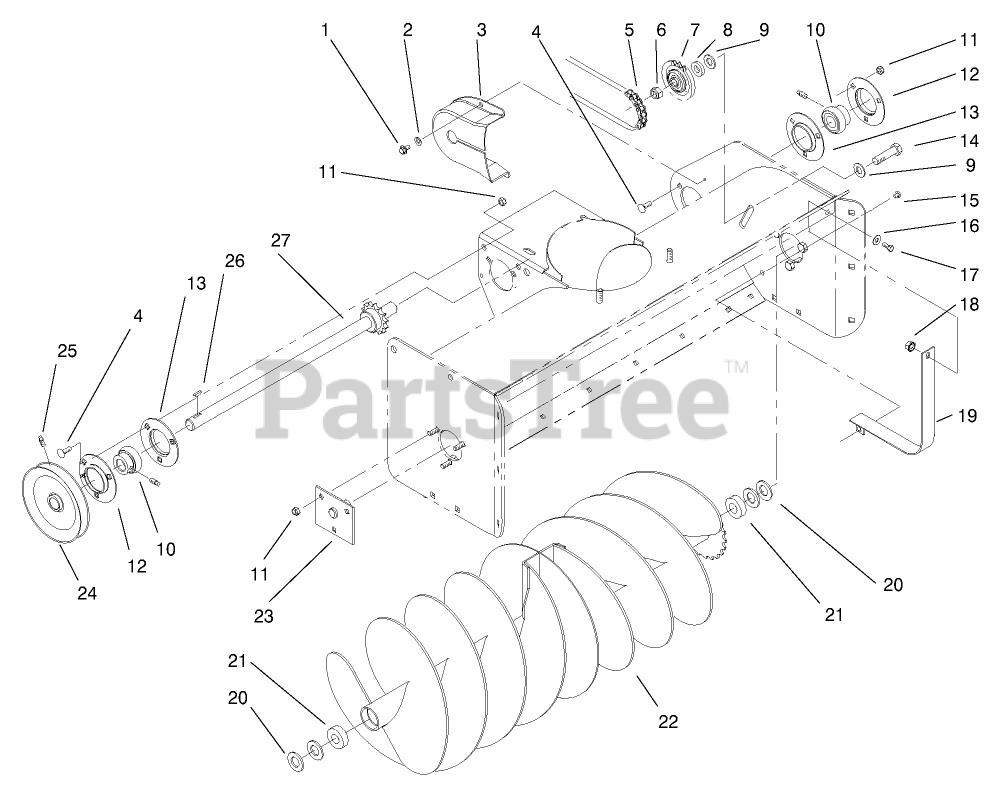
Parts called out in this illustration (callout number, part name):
1	SCREW-HWH
2	WASHER-FLAT
3	GUARD-CHAIN
4	BOLT-CARR
5	CHAIN-64 PITCHES
6	NUT-LOCK, NI
8	SPACER
9	WASHER-FLAT
10	BEARING AND COLLAR
11	NUT-LOCK, NI
12	FLANGE-ZERK RELUBE
13	FLANGE
14	SCREW-HH
15	SCREW-HHF
16	WASHER-FLAT
17	SCREW-HH
18	NUT-KEPS
19	GUARD-INNER
20	WASHER-FLAT
21	BEARING-BALL
23	SUPPORT ASM
24	PULLEY
25	SCREW-SQH
27	SPROCKET/SHAFT ASM
